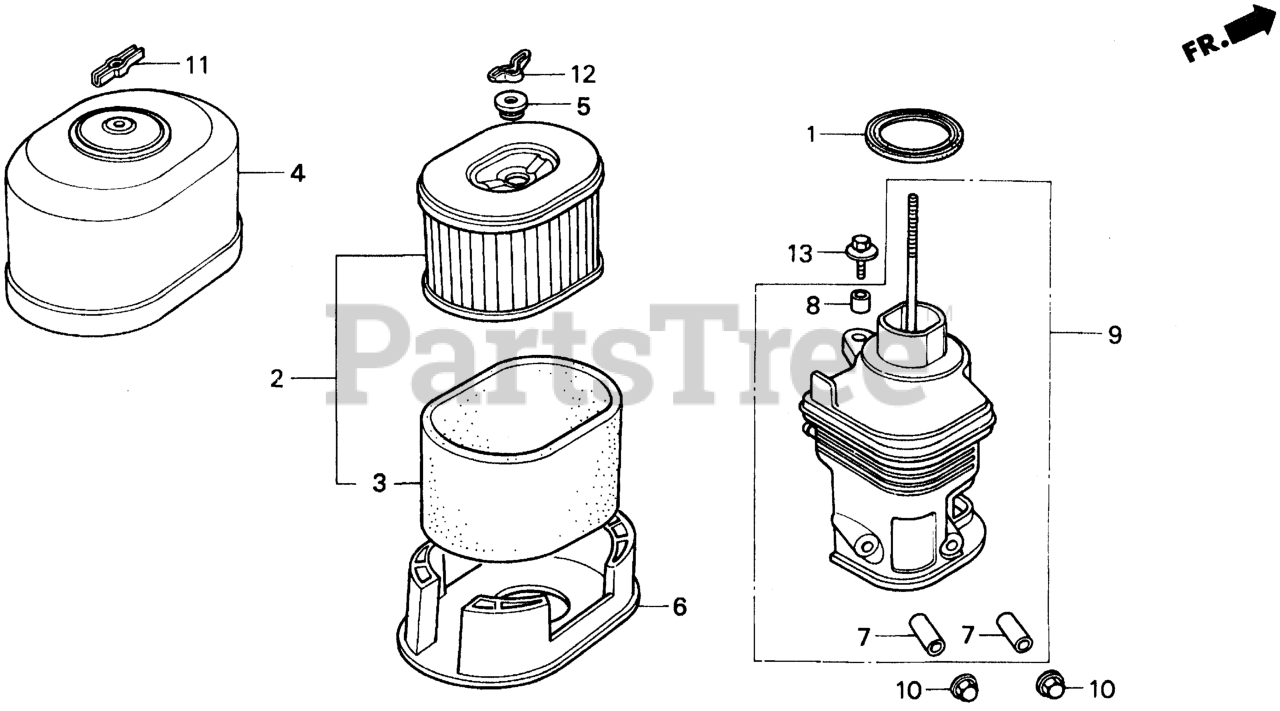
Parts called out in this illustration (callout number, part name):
1	GASKET, ELBOW
2	ELEMENT, AIR CLEANER
3	FILTER (OUTER)
4	COVER, AIR CLEANER (STD)
5	GROMMET, AIR CLEANER
6	NOSE, MUFFLER
7	COLLAR, AIR CLEANER
8	COLLAR B, AIR CLEANER
9	ELBOW, AIR CLEANER
10	NUT, CAP (6MM)
11	WINGNUT, AIR CLEANER COVER
12	WINGNUT, TOOL BOX SETTING
13	BOLT-WASHER (6X20)
